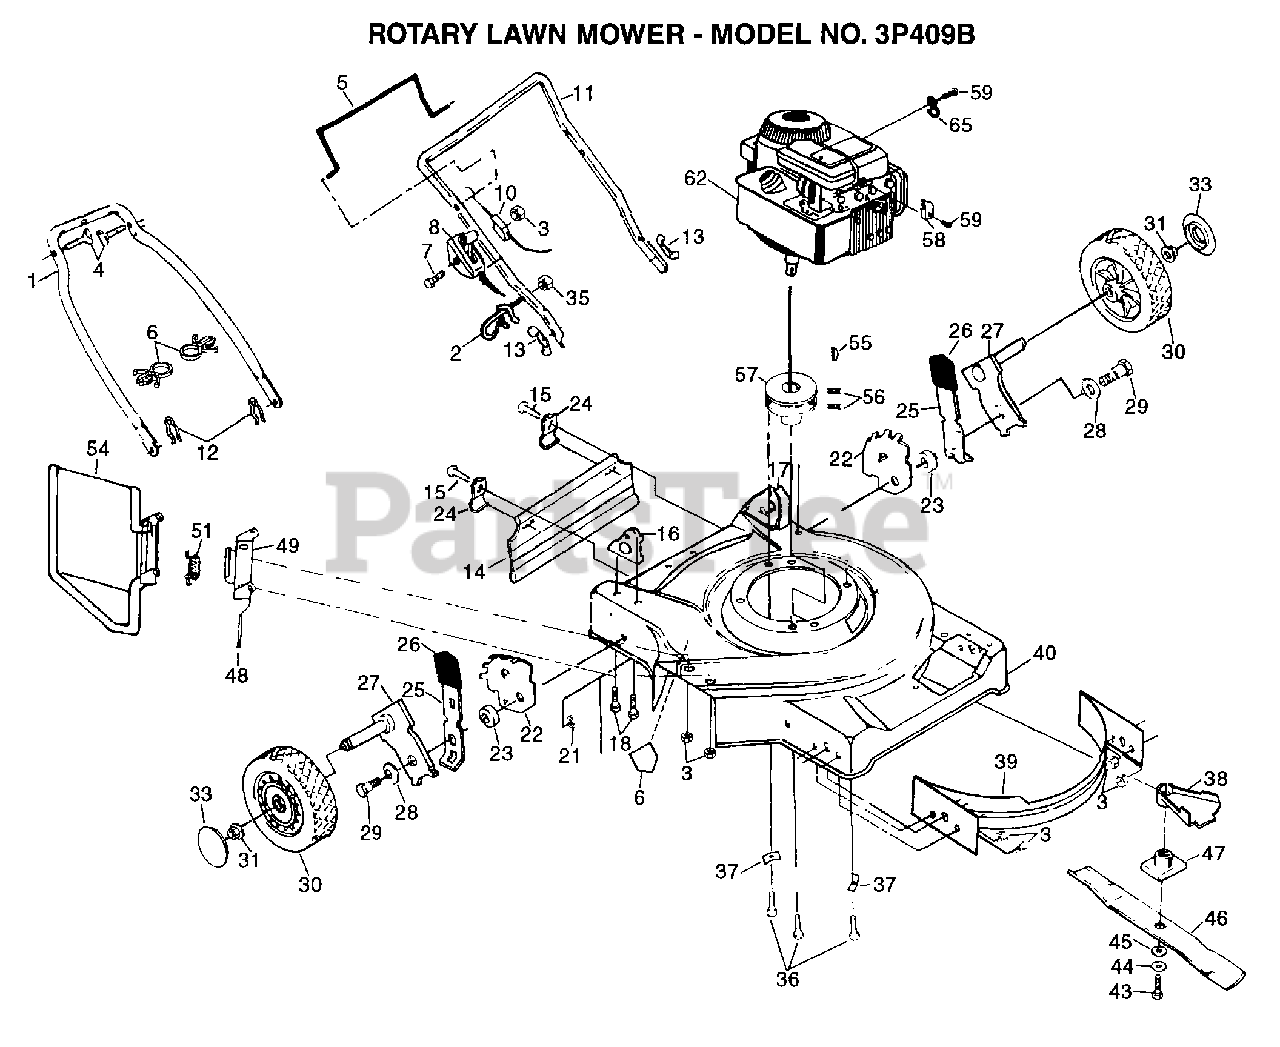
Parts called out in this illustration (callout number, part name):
2	ROPE GUIDE
4	BOLT.HANDLE.LM
5	BAIL.CNTRL.STD.BL
7	SCREW.HXHD.WASH.
8	CONTROL THROTTLE
10	"CABLE,ENG ZONE CO"
12	HAIRPIN COTTER
13	"NUT,WING PM"
14	SKIRT.REAR.FGD.22
15	TAPPING SCREW
16	HDLE BRKT ASSY.RH
17	HDLE BRKT ASSY LH
18	SCREW 5/16-18X3/4
21	LOCKNUT PM
22	BRACKET.ADJ.9POS.
23	SPACER.HEIGHT.ADJ
24	"BRKT,DEFL PM"
25	SPRING SELECTOR
26	KNOB PM
27	ARM.AXLE.ASM.BZP.
28	"WASHER, BELLEVIL."
29	BOLT SHLD 3/8-16
30	WHEEL.8X2.PR.RAD.
31	HEX FLANGE LOCKNT
33	HUB CAP
35	NUT
36	BOLT.ENG.3/8-16
39	BAFFLE FRONT 22SD
40	KIT.HSG.22SD.FWGD
43	SCREW
44	LOCKWASHER
45	"WASHER,HARDEN"
46	"BLADE.MULCH.22"""
47	ADAPTOR.BLADE.LM
48	ROD.HINGE.COMBI-C
49	BRACKET.HINGE.W/F
54	GUARD.DISCH.22SD.
55	HI PRO KEY PM
56	SCREW
57	ENGINE.PULLEY.FWG
58	CABLE CLAMP
59	SCREW PM
61	DECAL HYT
65	GUIDE CLIP PM
